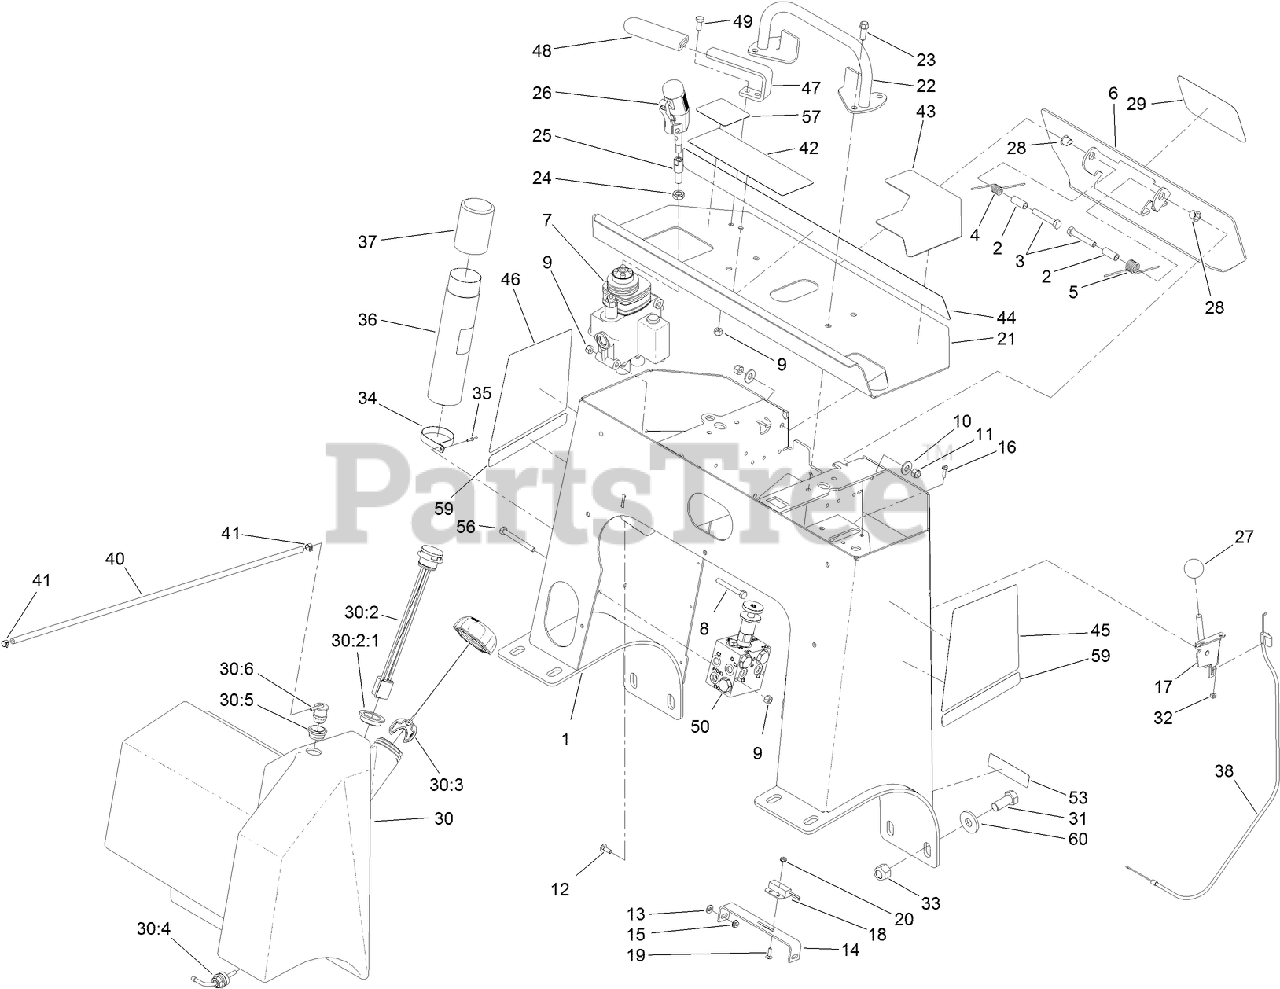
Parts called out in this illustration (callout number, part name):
2	SPACER-SPRING
3	SCREW-HH
4	SPRING-TORSION, LH
5	SPRING-TORSION, RH
6	PLATE-BACKUP
7	HYD VALVE ASM
8	SCREW-HH
9	NUT-LOCK, NI
10	WASHER-FLAT
11	NUT-LOCK, NI
12	BOLT-CARR
13	WASHER-FLAT
14	PLATE-SWITCH
15	NUT-KEPS
16	SCREW-HWH
17	LEVER-CONTROL
18	SWITCH-PROXIMITY
19	SCREW-CARR
20	NUT-KEPS
21	PANEL-CONTROL
22	BAR-REFERENCE
23	SCREW-TAPTITE
25	ADAPTER-HANDLE
26	TWO BUTTON HANDLE GRIP ASM
28	BUSHING-NYLINER
30	FUEL TANK ASM
30:2	GUAGE-FUEL
30:3	CAP-FUEL
30:4	FITTING-FUEL, BULKHEAD
30:5	GROMMET
30:6	VALVE-ROLLOVER
31	SCREW-HH
32	NUT-LOCK, NI
33	NUT-LOCK, NI
34	CLAMP-R
35	RIVET-POP
36	TUBE-MANUAL
37	CAP-HOUSING
38	CABLE-CONTROL
40	HOSE-FUEL
41	CLAMP-HOSE
42	DECAL-WARNING
43	DECAL-CONSOLE, LH
44	DECAL-CONSOLE, RH
45	DECAL-LOGO,LH
46	DECAL-LOGO,RH
47	BAR-ARM REST
48	GRIP-LEVER
49	SCREW-HH
50	SWEEP MANIFOLD ASM
53	DECAL-ARRESTER, SPARK
56	SCREW-HH
57	DECAL-JOYSTICK
59	DECAL-INTELLISWEEP
60	WASHER-HARDENED
